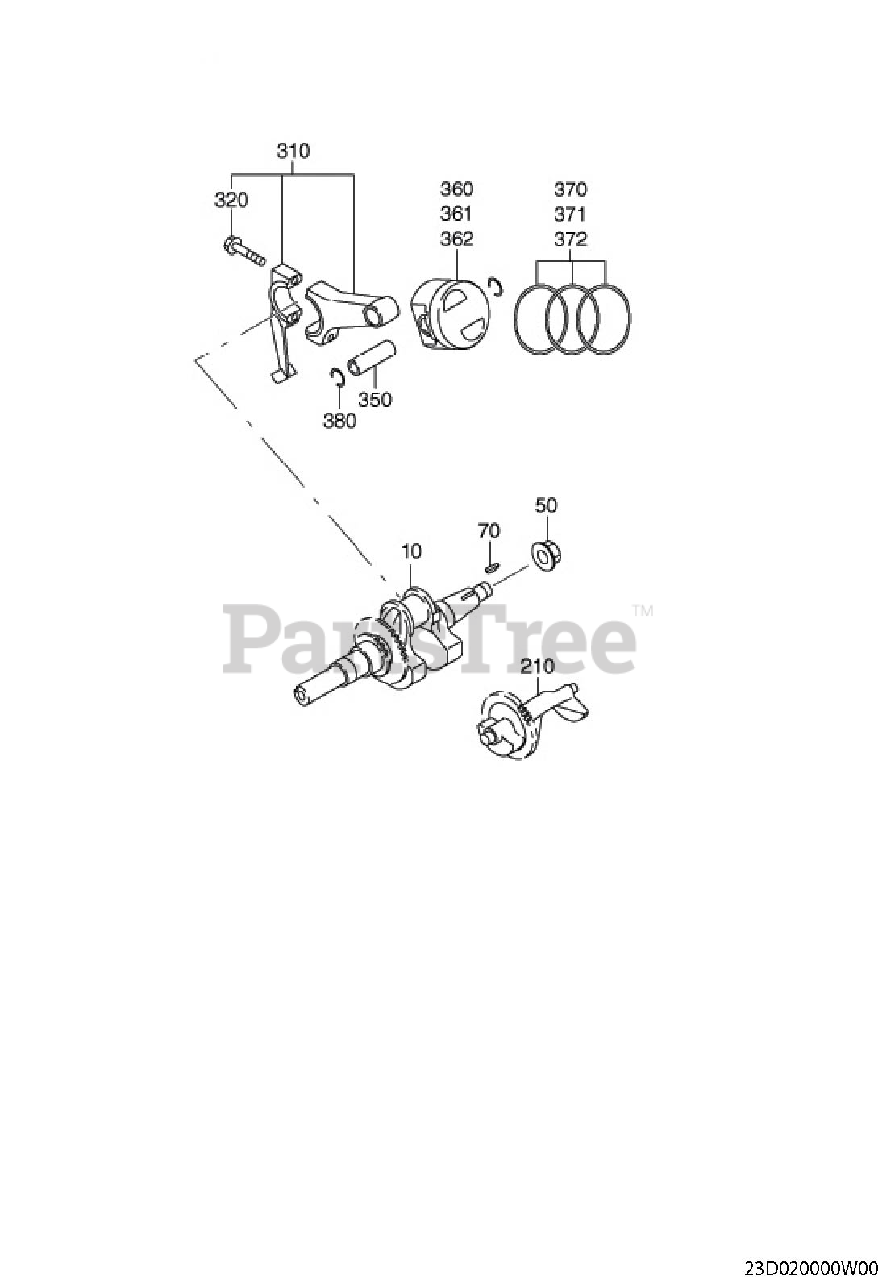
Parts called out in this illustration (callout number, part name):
10	CRANK SHAFT CP
50	FLANGE NUT
70	WOODRUFF KEY
210	BALANCER SHAFT
310	CONNECTING ROD AY
320	FLANGE BOLT
350	PISTON PIN
360	PISTON
361	PISTON
362	PISTON
370	PISTON RING SET
371	PISTON RING SET
372	PISTON RING SET
380	CLIP
